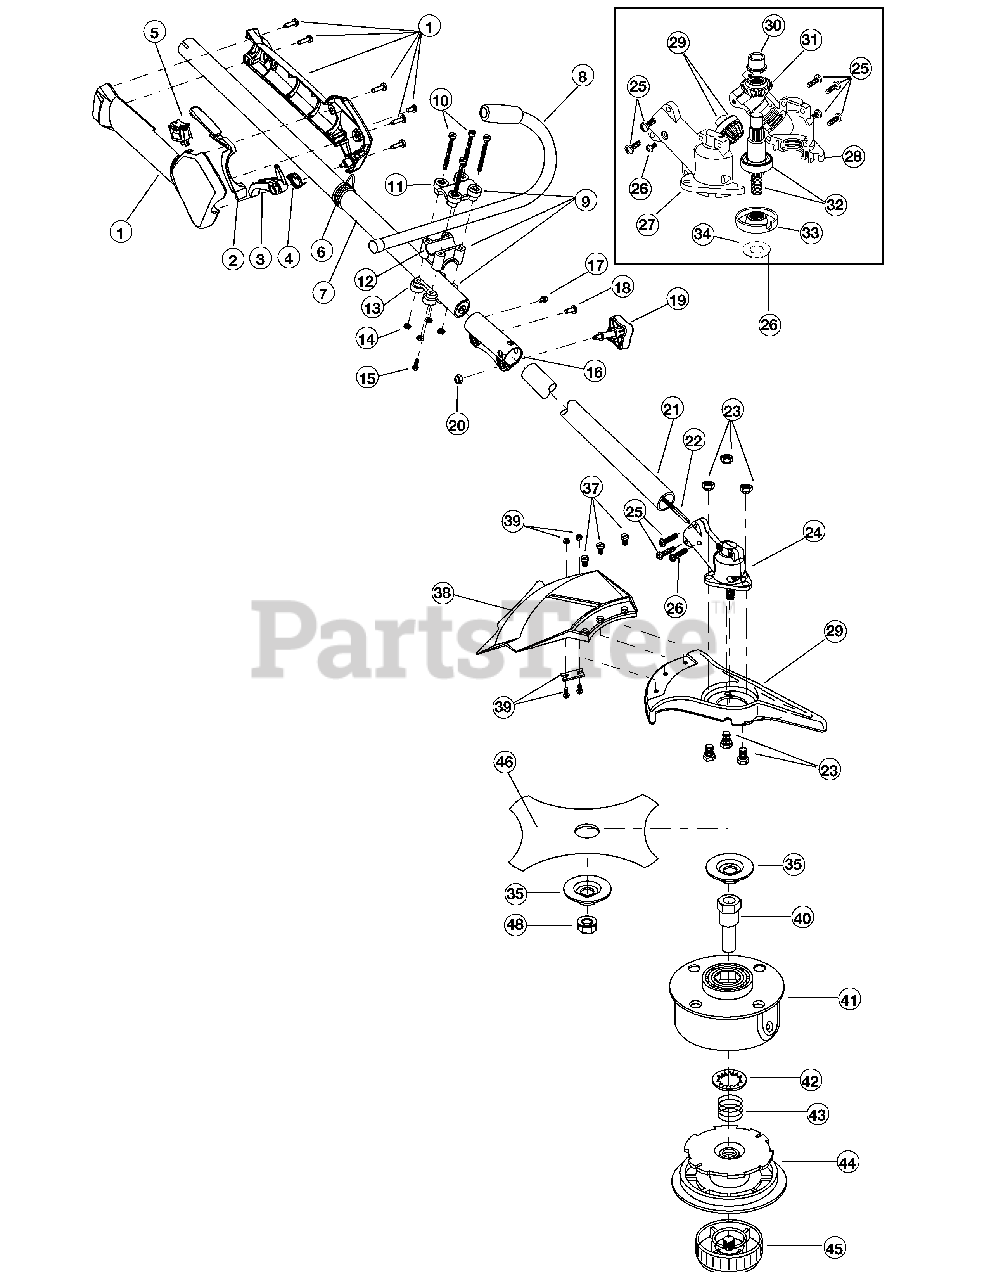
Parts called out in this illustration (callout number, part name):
1	Throttle Housing Assembly (includes 2-4)
2	Throttle Trigger Lock-Out
3	Throttle Trigger
4	Throttle Trigger Spring
6	Harness Clip
7	Upper Drive Shaft Housing Assembly
8	J-Handle Assembly
9	Handle Bracket Assembly (includes 10-15)
11	Upper Handle Clamp
12	Middle Handle Clamp
13	Lower Handle Clamp
15	Anti-Rotation Screw
16	Split Boom Coupler (includes 17-20)
19	Adjustment Knob
20	Knob Retaining Nut
21	Lower Drive Shaft Housing Assembly
22	Lower Flexible Drive Shaft
23	Shield Mount Screw Assembly
24	2 piece Gearbox Assembly (includes 25-35)
25	Gearbox Mounting Hardware
26	Anti-Rotation Screw
27	Right Housing
28	Left Housing
29	Pinion Gear Assembly
30	Output Shaft Bushing
31	Output Shaft Gear
32	Output Shaft Assembly (includes 30 & 31)
33	Blade Driver
35	Retaining Washer
36	Blade Shield/Shield Mount
37	Shield Mounting Screw
38	Shield Assembly (includes 39)
39	Blade Assembly
40	Spool Shaft
41	Outer Spool Assembly (includes 42)
42	Retainer
45	Bump Head Knob Assembly
46	4-Tooth Blade
48	Nut
